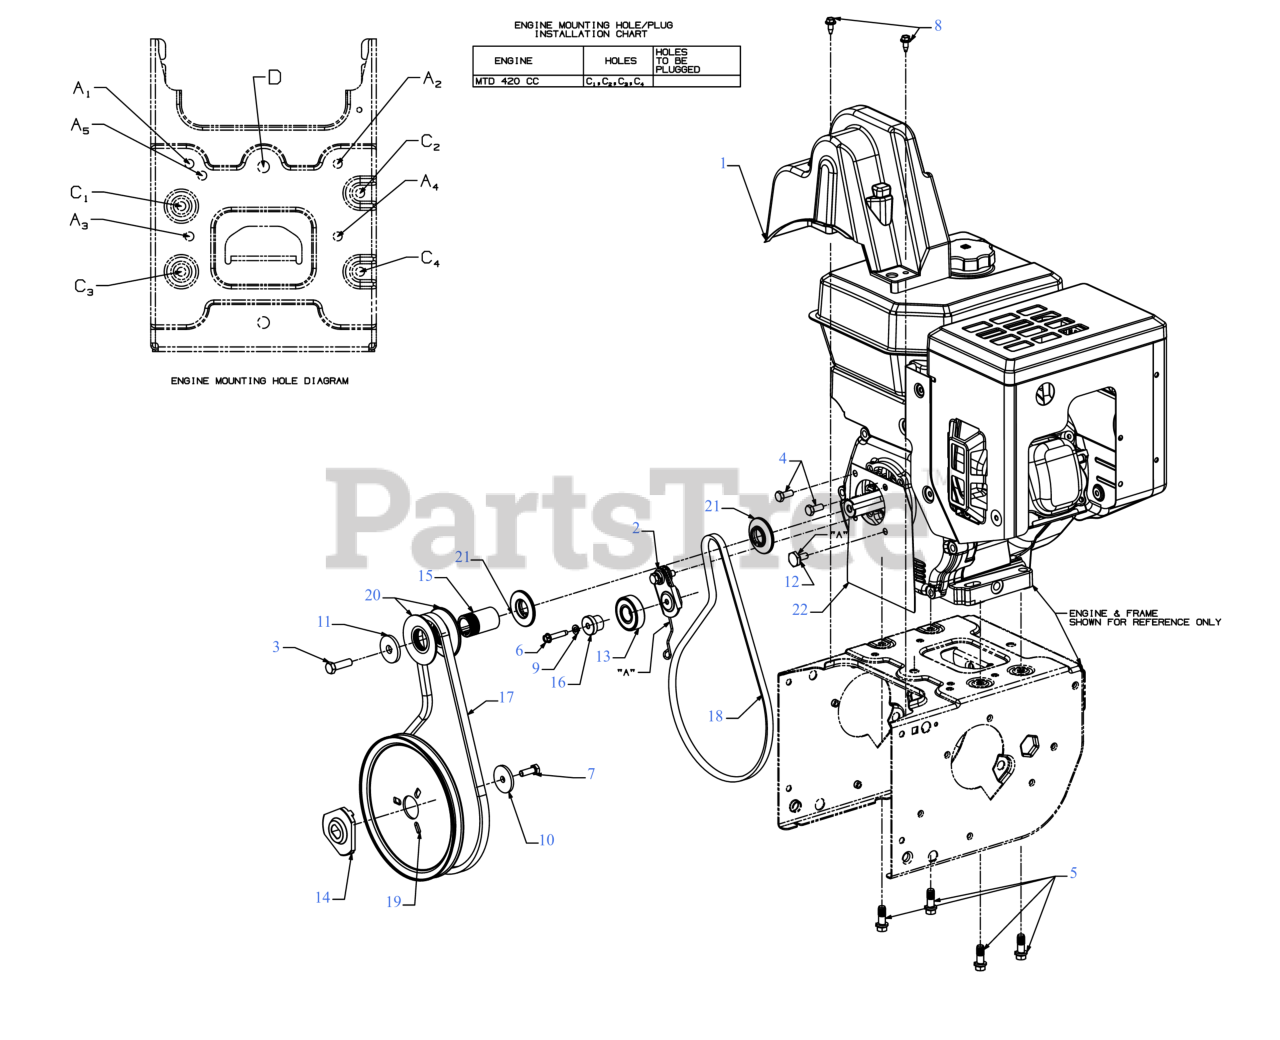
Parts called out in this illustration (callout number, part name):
1	BELT COVER (LARGE BLOCK)
3	SCREW 3/8-24X1.25
4	SCREW 5/16-24 x .750 GR5
5	SCREW 3/8-16 x 1
6	SCREW 1/4-20 x 1.25
7	SCREW 5/16-24 x .875 GR5
8	SCREW 1/4-20X.625
9	LOCK WASHER
10	FLAT WASHER
11	FLAT WASHER .45 x 1.5 x .172 HT
12	SHOULDER SCREW
13	BALL BEARING
14	ADAPTER PULLEY .75 DIA W/DD
15	PULLEY SPACER
16	SHOULDER SPACER
17	BELT-.500 x 37.00
18	V-BELT 3/8 x 35.68"
19	AUGER PULLEY
20	HALF PULLEY 4L V x 2.6 OD
21	HALF PULLEY-3/8 V x 1.7160
22	ENGINE PLATE (FRONT COVER)
